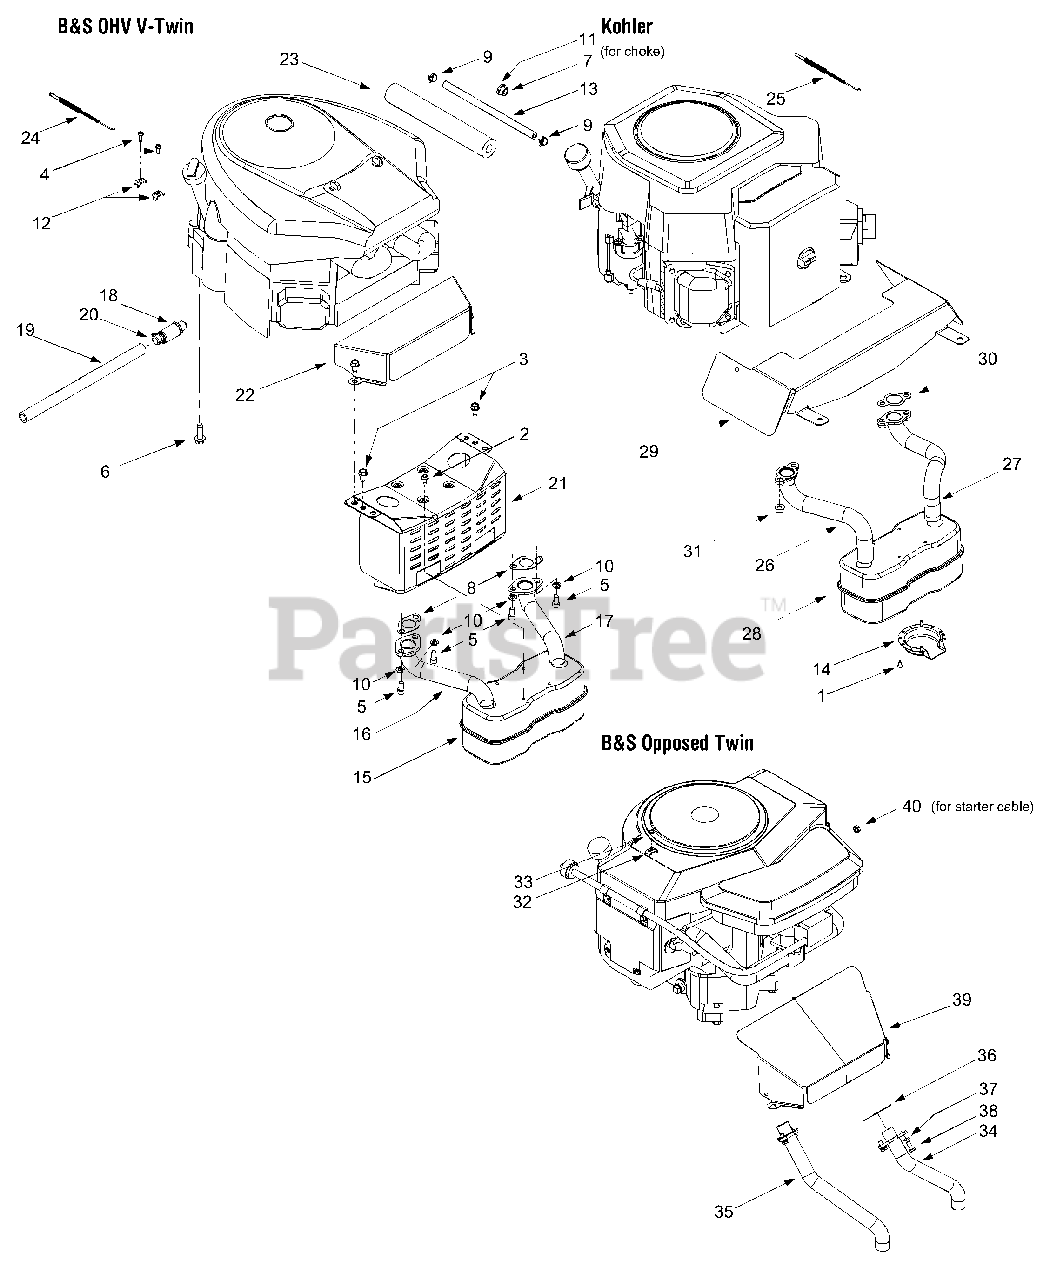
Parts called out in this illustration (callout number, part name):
1	Self-tapping Screw, #8-18 x .5
2	Self-tapping Screw, 1/4-20 x .5
3	Self-tapping Screw, 5/16-18 x .625
4	Screw, #10-32 x .625 (B&S OHV V-Twin)
5	Socket Cap Screw, 5/16-18 x .625
6	Self-tapping Screw, 3/8-16 x 1.25
7	Hex Nut, 3/8-16
8	Exhaust Gasket (B&S OHV V-Twin)
9	Hose Clamp
10	Lock Washer, 5/16
11	Flat Washer
12	Casing Clamp (B&S OHV V-Twin)
13	Fuel Line Hose
14	Muffler Deflector
15	Muffler, Twin Inlet (B&S OHV V-Twin & Opposed Twin)
16	RH Exhaust Pipe (B&S OHV V-Twin)
17	LH Exhaust Pipe (B&S OHV V-Twin)
18	Oil Drain Valve
19	Oil Drain Hose
20	Oil Drain Cap
22	Engine Heat Shield (B&S OHV V-Twin)
23	Foam (fits over fuel line)
24	Throttle Cable (B&S OHV V-Twin & Opposed Twin)
25	Throttle Cable (Kohler)
26	RH Exhaust Pipe (Kohler)
27	LH Exhaust Pipe (Kohler)
28	Muffler, Twin Inlet (Kohler)
29	Engine Heat Shield (Kohler)
30	Exhaust Gasket (Kohler)
31	Flange Nut, M8 x 1.25-6 (Kohler)
32	Clamp, 9/16 (B&S Opposed Twin)
33	Screw, #10-16 x .5 (B&S Opposed Twin)
34	LH Exhaust Pipe (B&S Opposed Twin)
35	RH Exhaust Pipe (B&S Opposed Twin)
36	Exhaust Gasket (B&S Opposed Twin)
37	Lock Washer, 1/4 (B&S Opposed Twin)
38	Hex Screw, 1/4-20 x .620 (B&S Opposed Twin)
40	Hex Sems Nut, 1/4-20 (B&S Opposed Twin)
